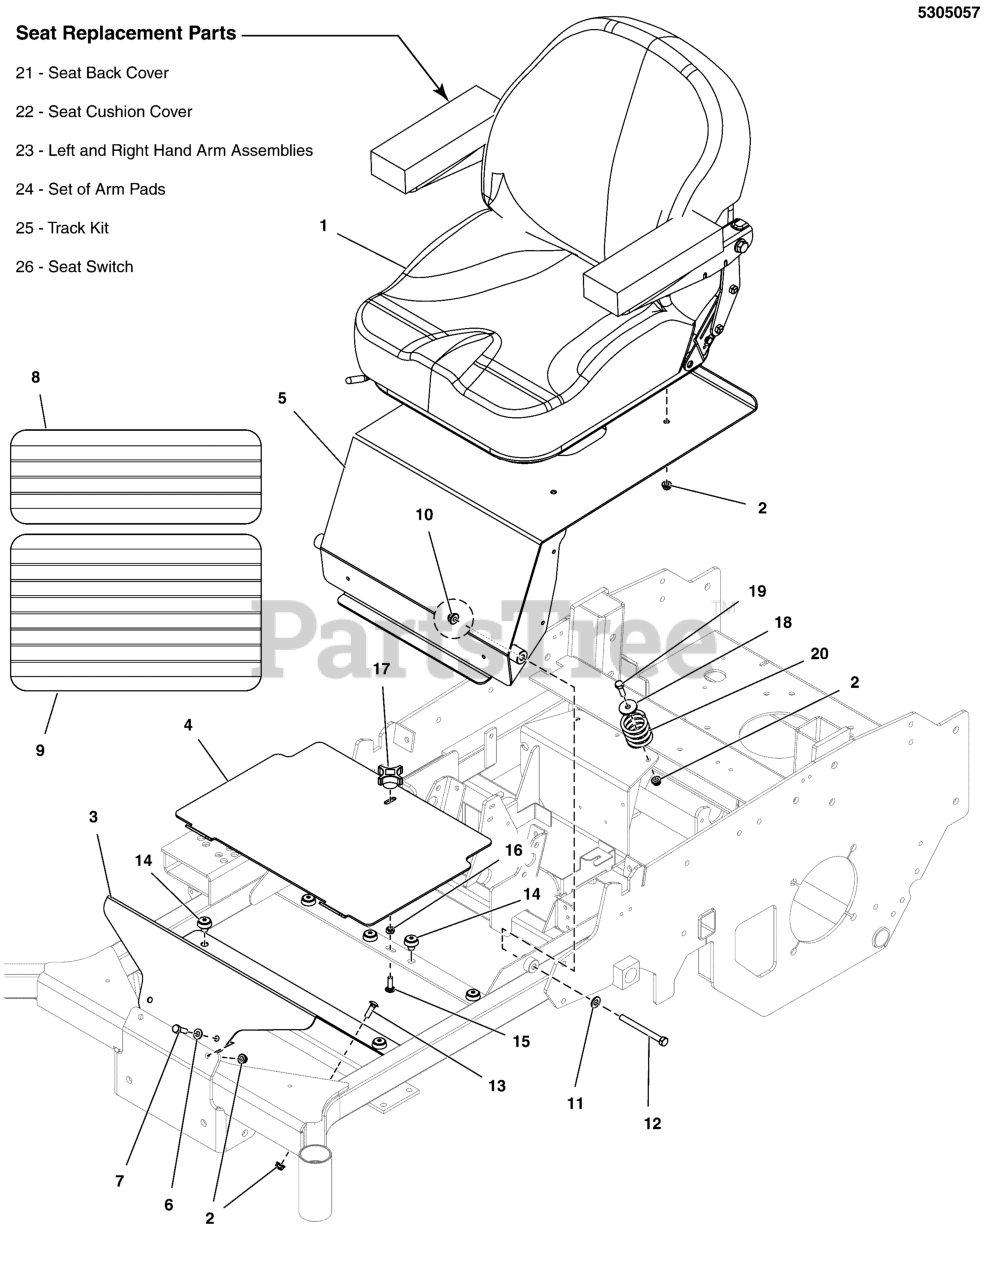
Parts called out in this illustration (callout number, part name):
1	SEAT, C13, SEAT'SINC, 2016, W/SWITCH
2	NUT, 5/16-18 HEX NYLOCK FLANGE
3	PLATE, FLOOR, NON REMOVABLE - RED
4	PLATE, FLOOR, REMOVABLE, IS700 - RED
5	ASSM, SEAT PLATE W/DECALS, S150XT-DOM
6	WASHER, 5/16" SAE
7	BOLT, 5/16-18 X 1 GD5 CZ
8	SAFETY WALK, FLOOR REST, 6.00 X 16.00
9	SAFETY WALK, FLOOR PLATE, S50X, 10X16
10	NUT, 3/8-16 HEX NYLOCK FLANGE
11	WASHER, 3/8 SAE
12	BOLT, 3/8-16 X 4" GD5 CZ
13	BOLT, 5/16-18 X 3/4, CARRIAGE, GD5, CZ
14	MNT, VBRTN, RBBR
15	BOLT, 5/16-18 X 1-1/4, CARRIAGE, GD5, CZ
16	NUT, 5/16-18, HEX, CNTR LK,ZINC PHOS/OIL
17	KNOB-INT THR .312-18 4-ARM 2.12WD 1.06LG
18	WASHER, .34 X 1.25 X 10 GA
19	BOLT, 5/16-18 X 1-1/2 GD5 CZ
20	SPRING, SEAT SUPPORT
21	BACK COVER, C13 SEAT
22	CUSHION COVER, C13 SEAT
23	ARM ASM, LH & RH, C13 SEAT
24	ARM PAD, C13 SEAT
25	TRACK KIT, C13 SEAT
26	SWITCH, SEAT
